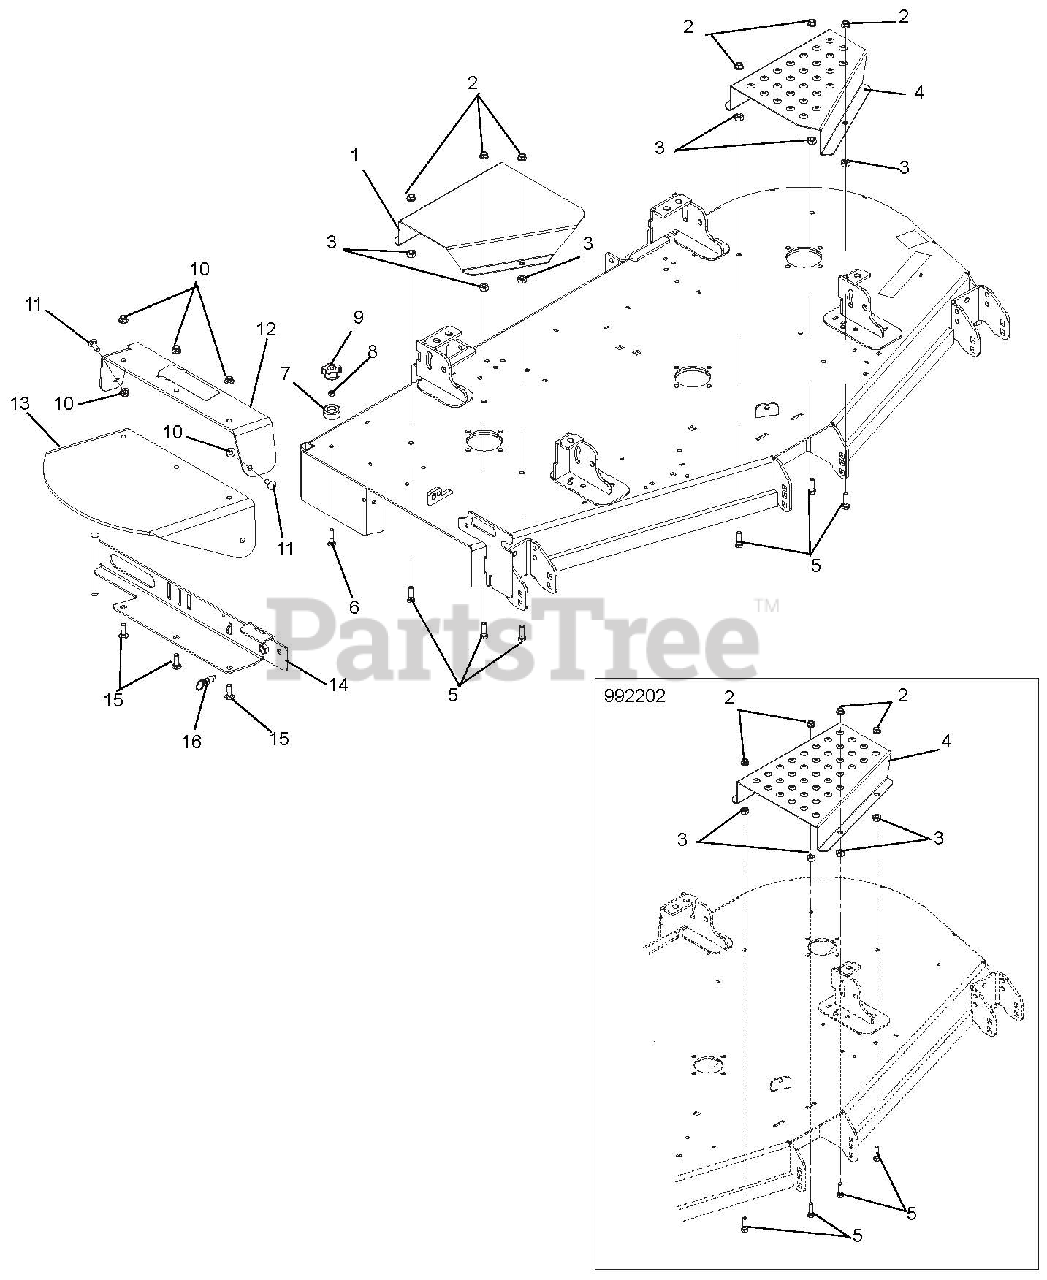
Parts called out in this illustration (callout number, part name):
1	Guard, Right Hand Deck Belt,60-66
1	Guard, Right Hand Deck Belt, 52
2	Nut, Spin Lock-Flange .375-16
3	Nut, Heavy Hex .38-16
4	Guard, Left Hand Deck Belt, 60
4	Guard, Left Hand Deck Belt, 66
4	Guard, Left Hand Deck Belt, 52
5	Bolt, Hex .38-16 x 1.25 Grade 5
6	Bolt, Round Head Square Neck .31-18 x 1.50 Grade 5
8	Nut, Locking-Center .31-18
9	Knob, Clamping, .312-18 Nyloc
10	Nut, Locking Nylon Flange .38-16
11	Bolt, Round Head Square Neck .38-16 x 1.00 Grade 5
12	Support, Rubber Discharge Chute
13	Chute, Rubber Discharge
14	Discharge Chute Mounting Weldment
15	Bolt, Round Head Square Neck .38-16 x 1.25 Grade 5
16	Pull Pin, .50-13 Thread x .310 Diameter Plunger
